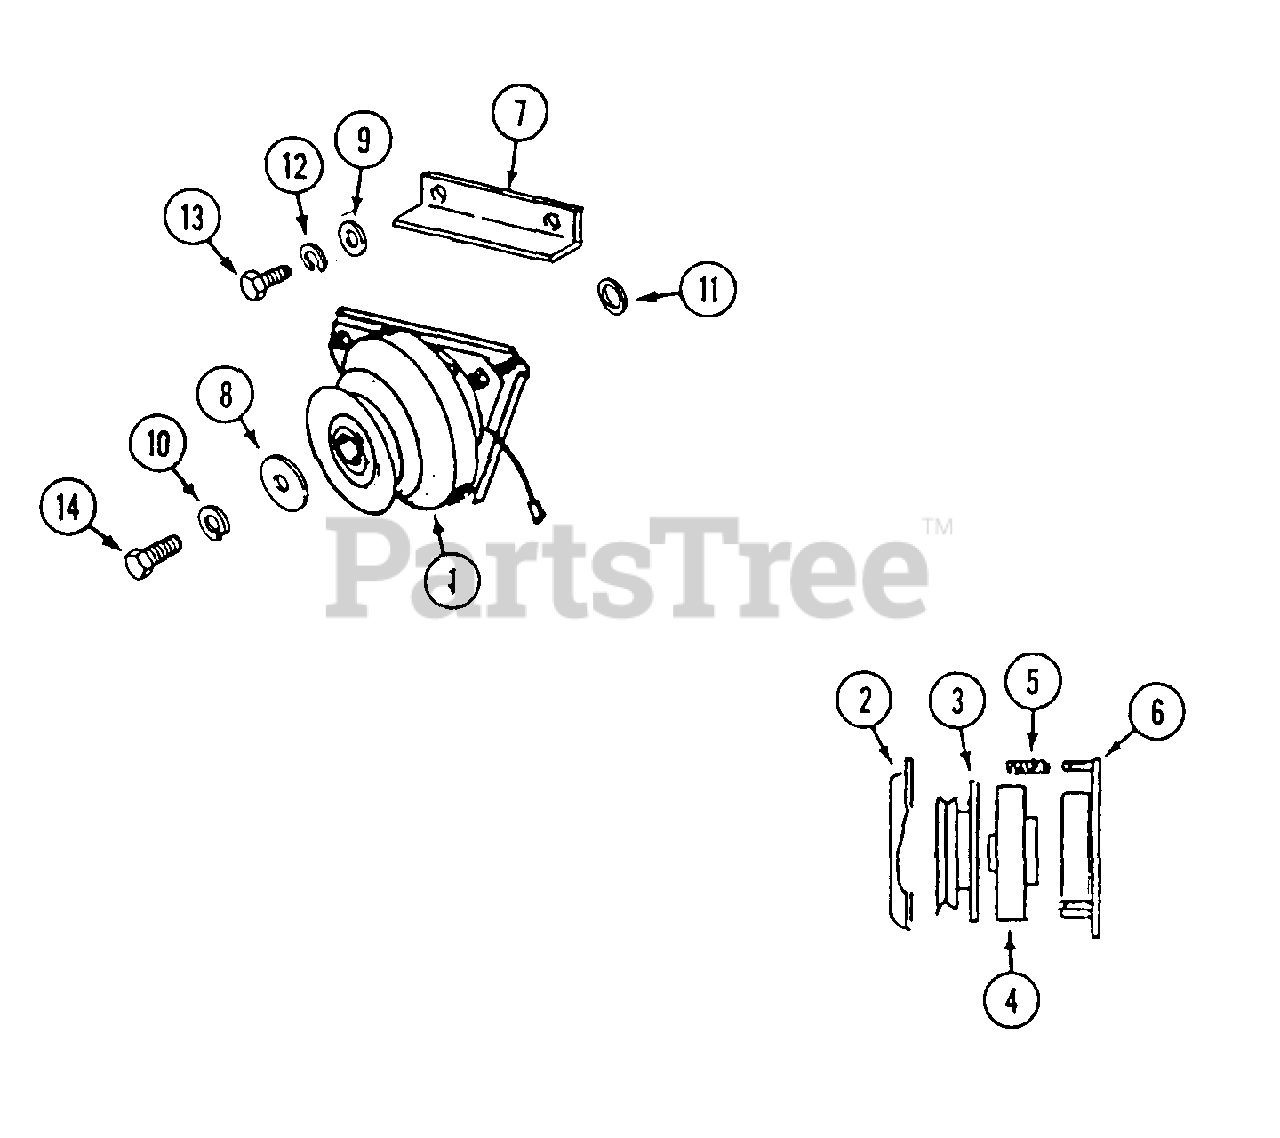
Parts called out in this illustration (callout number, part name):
1	CLUTCH ASSEMBLY
2	BRAKE - clutch
3	ARMATURE - clutch
4	ROTOR - clutch
5	KIT - spring and nut (3 each)
6	COIL - clutch
7	BRACKET - clutch stop
8	WASHER - retaining
9	WASHER - 7/16"
10	LOCKWASHER - 3/8"
11	WASHER - 1-1/8"
12	LOCKWASHER - 7/16"
13	BOLT - 7/16" - 14 x 3/4"
14	BOLT - 3/8" - 24 x 1-1/4"
